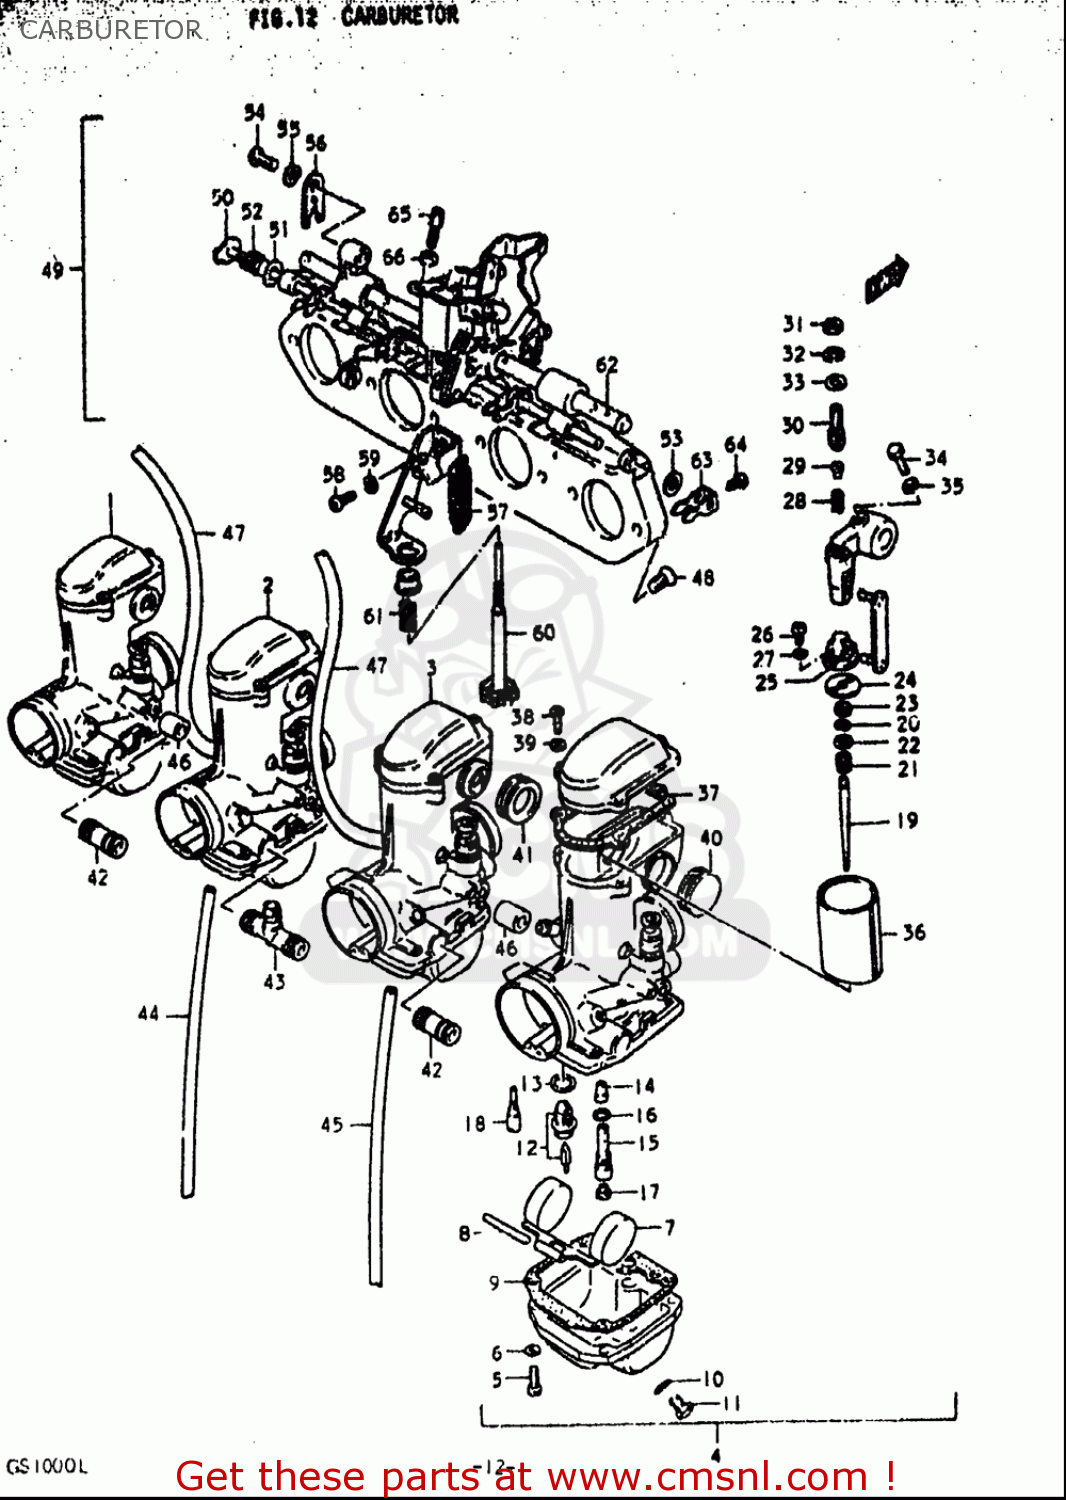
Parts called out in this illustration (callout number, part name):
5	SCREW 4X16
6	WASHER,LOCK
7	FLOAT
8	PIN,FLOAT
9	GASKET,FLOAT CHAMBER (NAS)
10	O RING
11	SCREW
12	VALVE ASSY,NEEDLE
13	GASKET,VALVE SEAT (NAS)
15	PIPE,BLEEDER
16	O RING
17	JET,MAIN(95)
18	JET,PILOT
19	NEEDLE,JET
20	CLIP
21	SPRING
22	WASHER,JET NEEDLE
23	RING
26	SCREW
27	WASHER,LOCK
31	NUT
32	WASHER,LOCK
33	WASHER
34	BOLT
35	WASHER,LOCK
37	GASKET (NAS)
38	SCREW 4X16
39	WASHER,LOCK
41	SEAL
46	HOSE(6X10X600)
47	HOSE(4.5X8.5X600)
48	SCREW(6X14)
51	WASHER
53	WASHER,STARTER SHAFT
54	SCREW
55	WASHER,LOCK
57	SPRING,THROTTLE RETURN
58	SCREW
59	WASHER,LOCK
64	SCREW
65	ADJUSTER,CABLE
66	NUT
